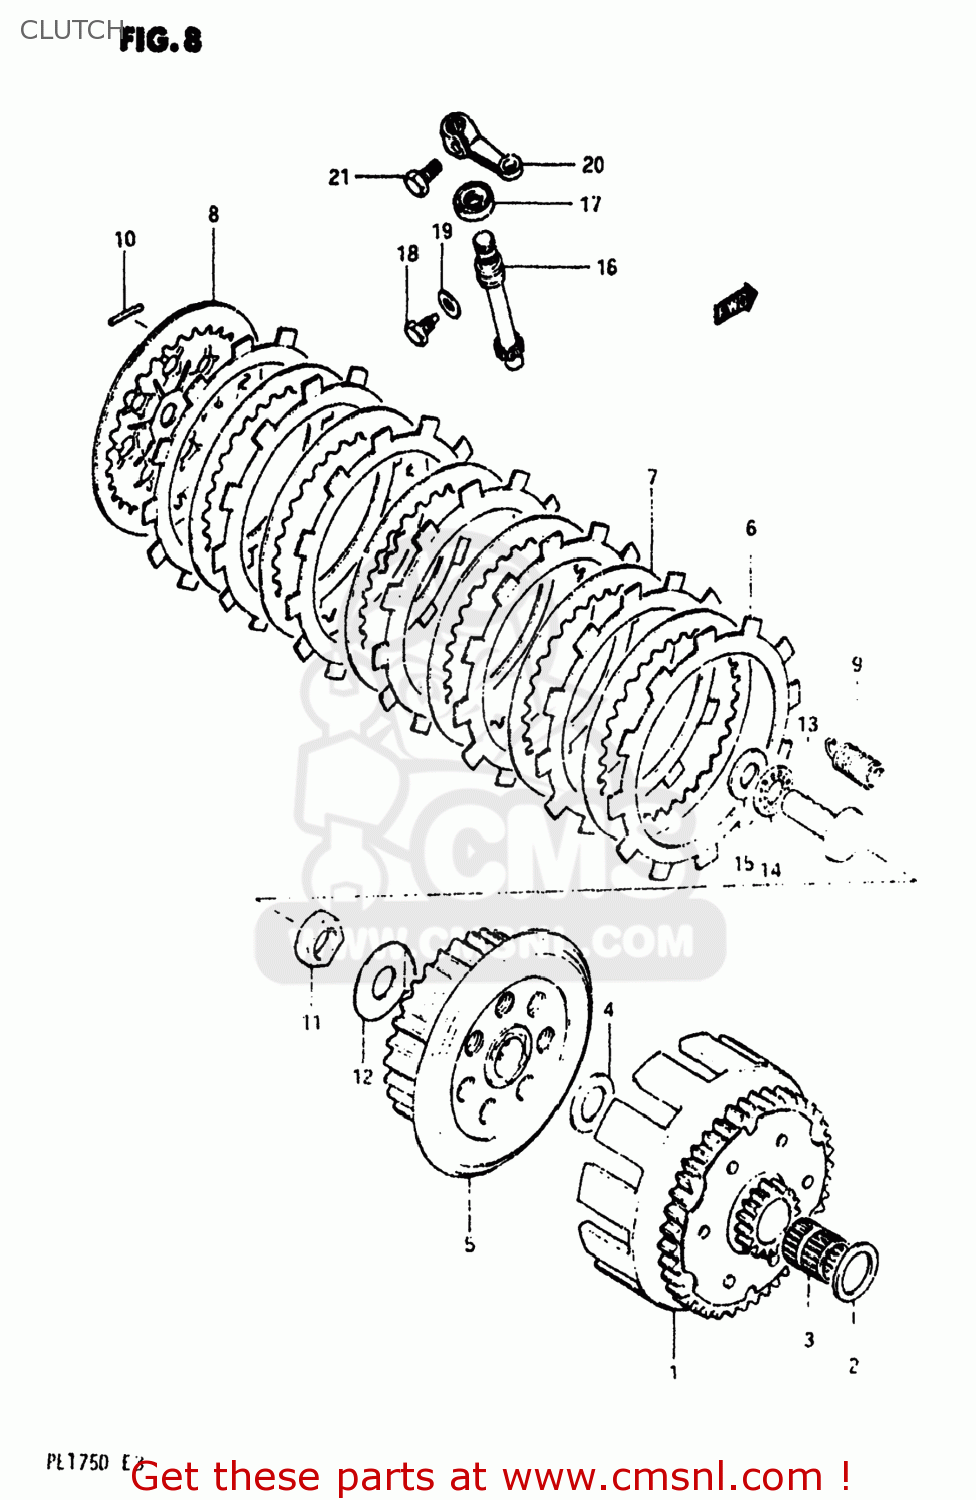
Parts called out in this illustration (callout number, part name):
1	GEAR ASSEMBLY,PRIMARY DRIVE
2	WASHER
3	BEARING(20X25X26)
4	WASHER
5	HUB,CLUTCH SLEEVE
6	PLATE,CLUTCH DRIVE
7	PLATE,CLUTCH DRIVEN
8	PLATE,CLUTCH PRESSURE
9	SPRING
10	PIN(2.5X19.8)
11	NUT
12	WASHER,LOCK
13	RACK,CLUTCH RELEASE
14	BEARING(10X22X2.8)
15	WASHER(10.1X21.4X0.8)
16	PINION,CLUTCH RELEASE
17	SEAL,OIL (10X17X5)
18	BOLT(6X12)
19	WASHER
20	ARM,CLUTCH RELEASE
21	BOLT, UPPER
